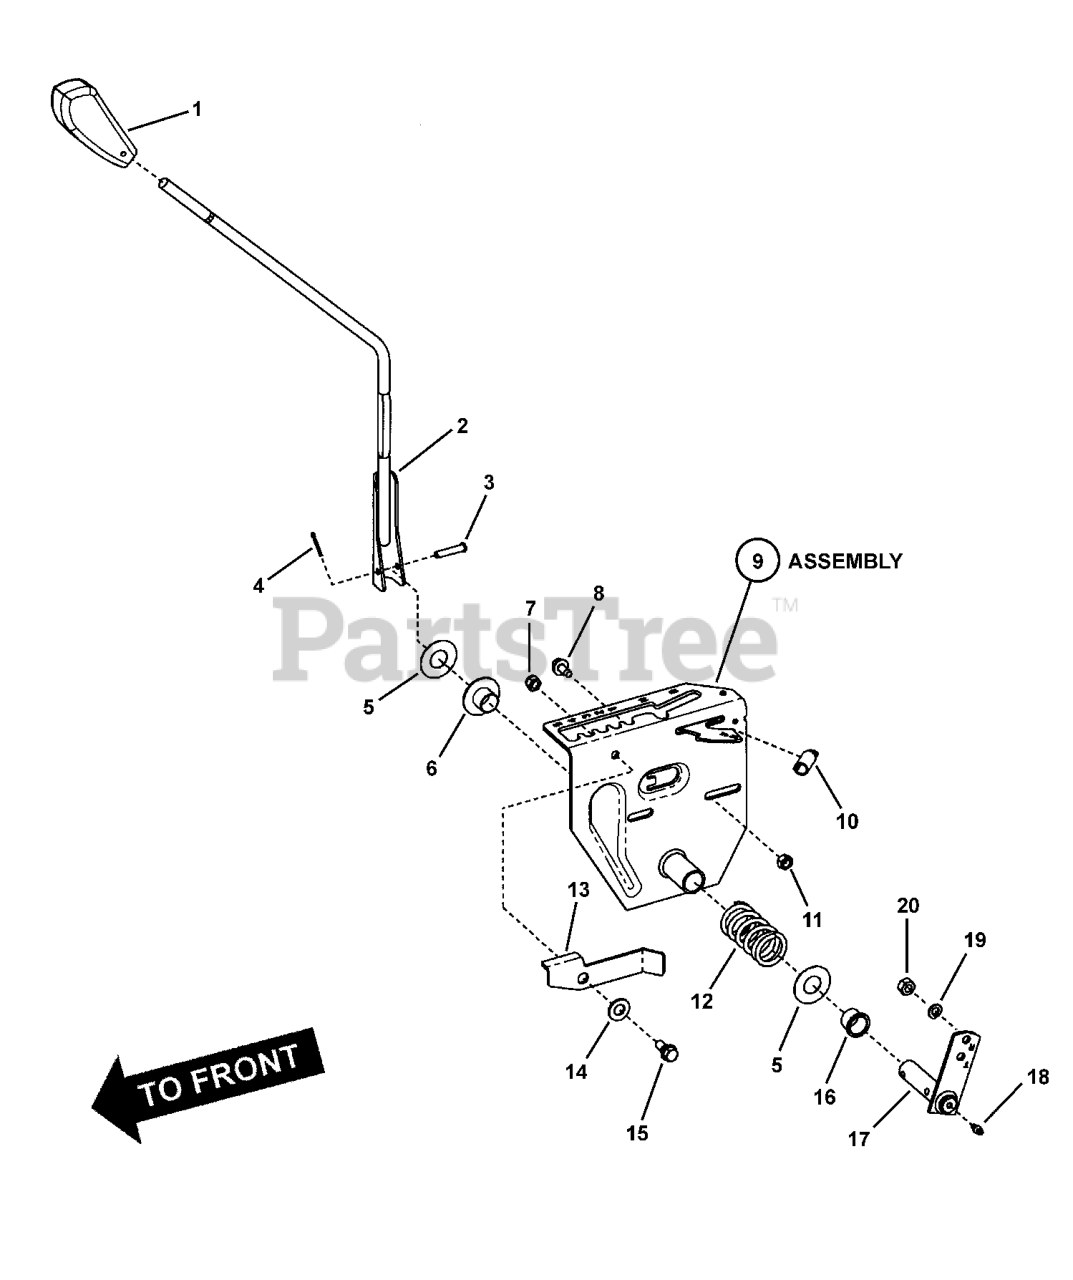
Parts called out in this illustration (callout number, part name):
1	GRIP, Shift Handle
2	WELDMENT, Shift Handle
3	PIN, 1/4 x 1-3/4" Tapered Clevis
4	PIN, 3/32 x 3/4" Cotter
5	WASHER, Thrust
6	BUSHING, 3/4 x 1.62 Flange (Nylon)
7	NUT, 5/16-18 Hex Nyloc
8	SCREW, 5/16-18 x 5/8" Hex Washer Self-Tap
9	ASSEMBLY, Speed Adjustment Latch
10	SPRING
11	NUT, 5/16-18 Hex, GR 5 or B
12	SPRING, Shift Detent
13	LEVER, Over-Ride
14	WASHER, .47 x .92 x .065 Flat
15	SHOULDER BOLT, 5/16-18
16	BUSHING, 3/4 x I.O. Flange (Nylon)
17	WELDMENT, Arm, Shift Handle (w/grease ftg. Hole)
18	LUBE FITTING, 3/16" Press-In
19	WASHER, .32 x .58 x .08 Split Lock
20	NUT, 5/16-24 Hex, GR 5
